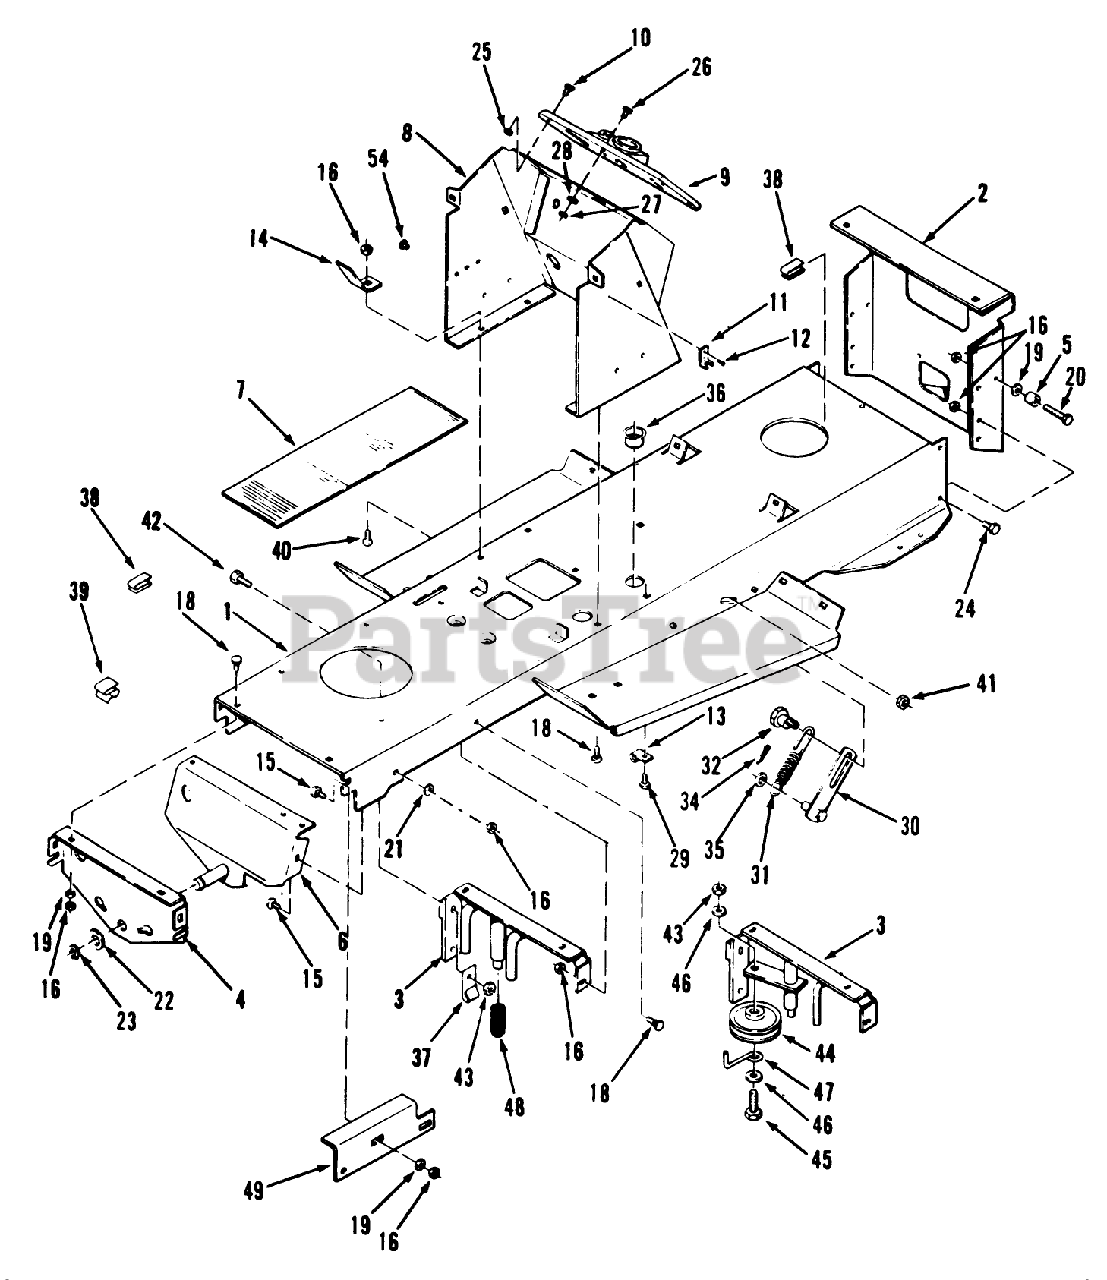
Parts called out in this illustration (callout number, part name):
1	FRAME *R
2	PLATE-DRAWBAR *R
4	PLATE SUPT - AXLE *R
7	PAD-FOOTREST
11	KEEPER-LATCH
13	J-CLIP
15	SCREW-CARR
16	NUT-LOCK, NI
19	WASHER-PLAIN
20	SCREW-HH
21	WASHER-LOCK, INTERNAL
22	WASHER
23	RING-RETAINING
24	SCREW-HH
27	NUT-HEX
28	WASHER-LOCK
31	SPRING
32	CAM-ADJUST
34	PIN-COTTER
35	WASHER-FLAT
36	BUSHING-NYLON 1.093
37	CLIP
39	CLIP-CABLE
41	NUT-LOCK, NI
42	SCREW-HH
43	NUT-LOCK, NI
45	SCREW-HH
46	WASHER-FLAT
54	PLUG-NYLON .250
